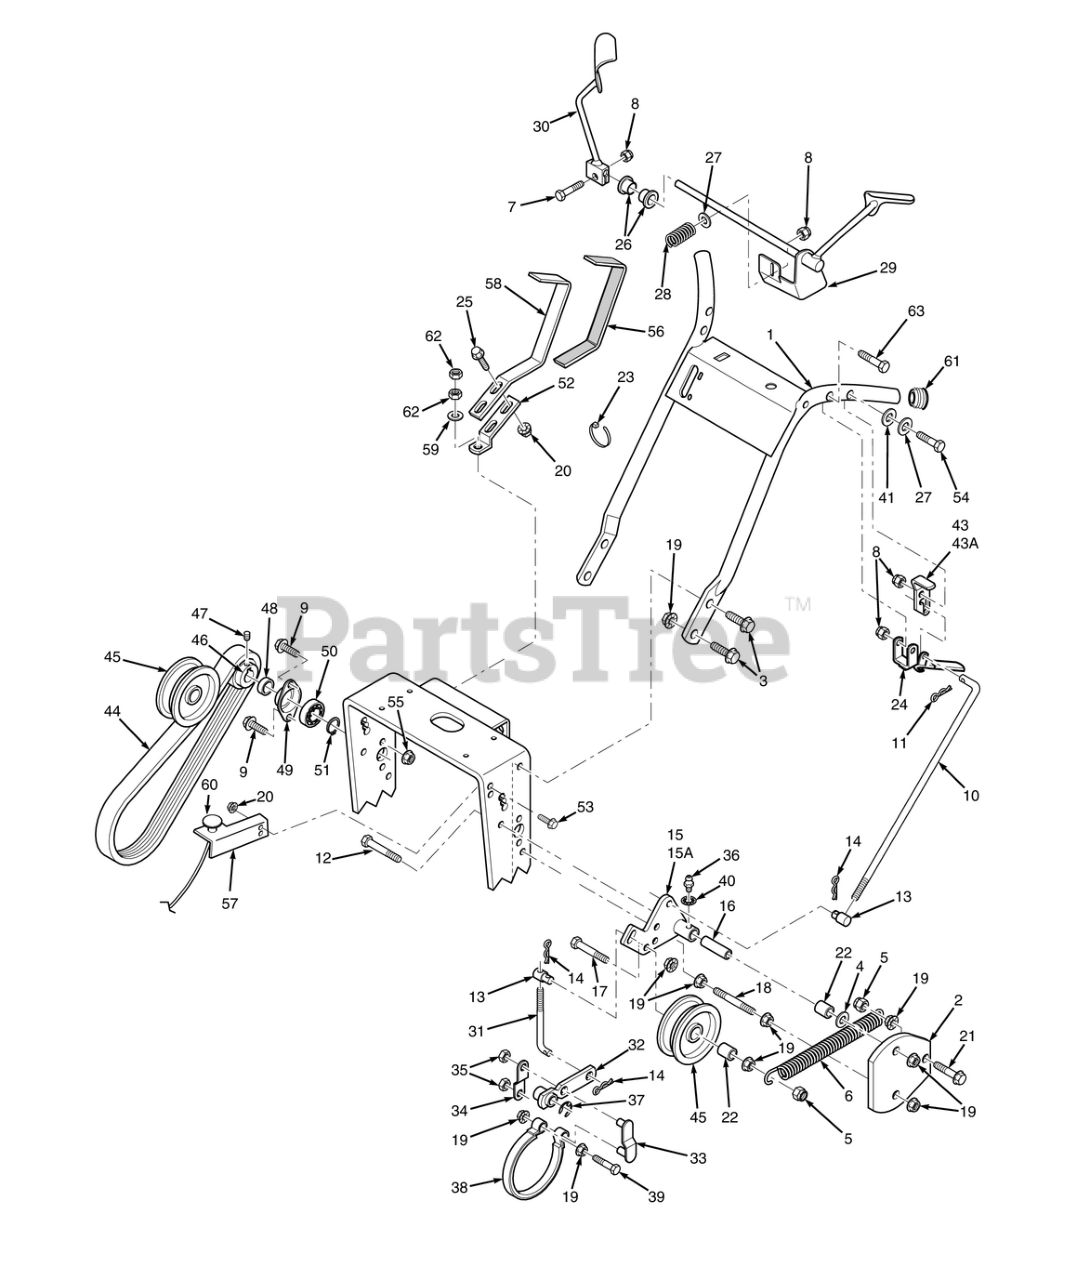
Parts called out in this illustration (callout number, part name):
1	Handle Assembly
2	BELT GUARD
3	Capscrew, 3/8-16 x 1.0" Serrated Flange Hex Hd
4	Flatwasher, 3/8" Special (.391 x .938 x .105)
5	HEX NUT, ELASTIC STOP LOCK, 3/8-16
6	Spring,Counter Balance
7	Bolt, 5/16 - 18 x 1 - 1/4" Hex Head
8	HEX NUT, ELASTIC STOP LOCK, 5/16-18
9	Bolt, Serrated Flange Hex Head 1/4 x 20 x 3/4"
10	Control Rod, Steering
11	HAIR PIN, .08 DIAMETER X 1-3/16"
12	Bolt, 3/8 - 16 x 4 - 1/2" Hex Head
13	SWIVEL JOINT, SPEED CONTROL ROD
14	COTTER PIN, HAIR - 0.94 X 1.62
15	Idler Bracket, RH
15A	Idler Bracket, LH
16	IDLER SLEEVE
17	Capscrew, Hex Head 3/8-16 x 3.25"
18	SUPPORT BELT GUARD
19	NUT, 3/8-16 SERRATED FLANGE HEX HEAD
20	Nut, Serrated Flange 5/16-18 (Right Front Engine Mounting, Briggs and Kohler Only)
21	CAPSCREW, 3/16 X 1-1/4" SERRATED FLANGE
22	Spacer, Idler
23	Cable Tie, .19 x 8.0"
24	Lever, Steering Control
25	Cpscrw, 5/16-18 x 1"Serrated Flange Hex Head
26	Bushing
27	Flatwasher, 5/16-.375 x .875 x .083 (35BV & 37BV-EFI)
28	Spring, Operator Presence
29	Operator Presence Lever, LH
30	Operator Presence Lever, RH
31	BRAKE ROAD
32	BRAKE LEVER
33	Link Weldment, Brake
34	BRAKE LINK PLATE
35	Nut, 3/8 Push - on
36	Greese Fitting, Straight 1/4 - 28
37	RETAINING RING, 5/8" EXTERNAL "E"
38	Brake Band Assembly
39	Capscrew, Hex Head 3/8-16 x 2.0"
40	1/4" INTERNAL TOOTH LOCKWASHER
41	Socket Head Capscrew #8-32 x 1/2"
42	Socket Head Capscrew #8 - 32 x 1/2"
43	Neutral Latch-RH 461241 Neutral Latch-LH
43A	Neutral Latch Assembly, LH
44	BELT, WHEEL DRIVE
45	Idler Pulley, Wheel Drive
46	Pulley, Jackshaft
47	Setscrew, Hex Socket Knurl Cup Pt. 5/16 - 18 (nylock)
48	SPACER, JACKSHAFT PULLEY
49	FLANGE, JACKSHAFT BEARING
50	BEARINGS, BALL, NEUTRAL RETURN
51	RETAINING RING, 5/8 EXT. - BASIC
52	Shift Lever
53	Capscrew, 5/16-18 x .75 Serrated Flange Hex Head
54	Bolt, Hex Head 5/16-18 x 2-1/2" (x3) (35BV & 37BV-EFI)
55	NUT, 1/4-20 SERRATED FLANGE HEX HEAD
56	Grip, Shift Handle
57	Bracket, Choke Mounting
58	Shift Lever Extension w/Grip
59	Flatwasher, 3/8" Special (.391 x .938 x .105)
60	Choke Control
61	Plug, Handle Bar
62	HEX NUT, 3/8-24 R.H. THREAD
63	Bolt, Hex Head 5/16-18 x 2-1/2" (35BV & 37BV-EFI)
64	Cap, Fuel Tank
